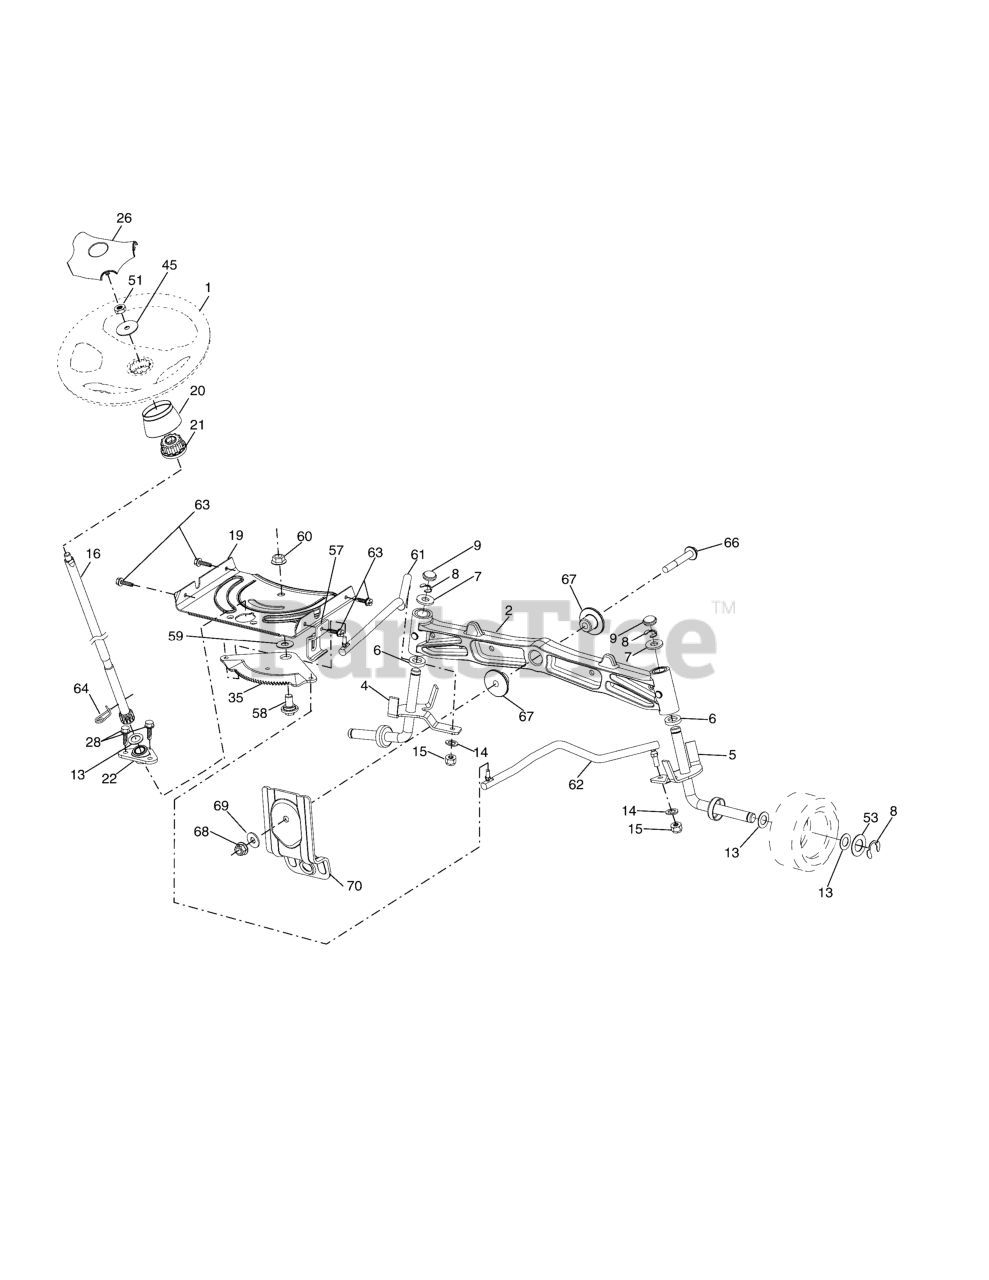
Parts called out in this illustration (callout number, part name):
1	Wheel, Steering
2	Axle Asm., Front
4	Spindle Asm., LH
5	Spindle Asm., RH
6	Washer, Thrust .75 x 1.230
7	Washer 25/32 x 1-5/8 x 16 Ga.
8	Ring, Clip #T5304-75
9	Cap, Spindle
13	Washer 25/32 x 1-1/4 x 16 Ga.
14	Washer Lock 3/8
15	Nut, Crown Lock 3/8-24 unf
16	Shaft Steering
19	Plate Steering
20	Boot, Steering
21	Adapter, Wheel Steering
22	Bushing, Strg. Blk
26	Insert, Wheel Steering
28	Screw 3/8-16 x 3/4
35	Gear, Sector Plate
45	Washer 9/16 x 2-3/8
51	Nut Hex Jam Toplock 1/2-20 unf
53	Washer Hardened .793 x 1.637 x .060
57	Bracket Upstop
58	Bolt Shoulder Sector Pivot CFM
59	Washer Thrust Sector Steering
60	Nut Flange Lock 5/8-11
61	Draglink, LH
62	Draglink, RH
63	Screw 5/16-18 x 3/4
64	Retainer Clip Spring Steering
66	Bolt Hex Fghd 7/16-14 x 3 Serr
67	Bushing PM Front Axle
68	Nut Lock Flange 7/16-14 Gr. 5
69	Washer 1.5 x .505 x .118
70	Bracket Deck Susp. Front
